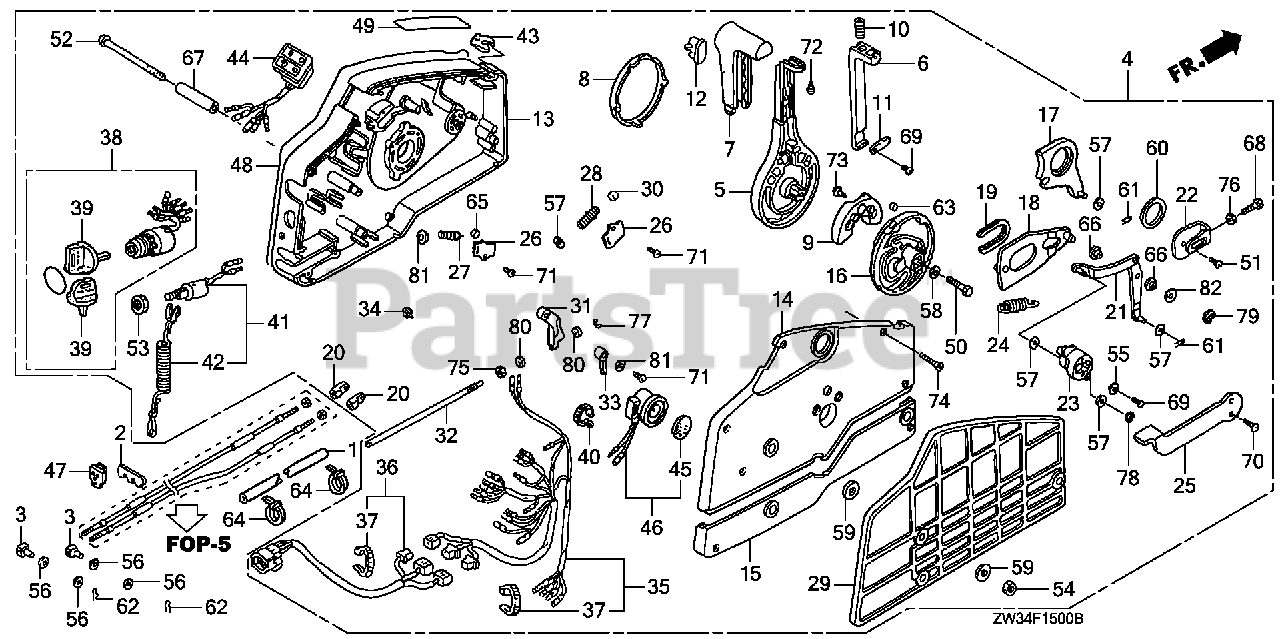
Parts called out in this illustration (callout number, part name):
4	S/R SW 2 LIGH MAN TL
4	BOX ASSY., REMOTE CONTROL (A/T)
4	BOX ASSY., REMOTE CONTROL (A/T)(HI-LEX)
5	HANDLE, REMOTE CONTROL
6	LEVER, HANDLE LOCK
7	GRIP, REMOTE CONTROL HANDLE
8	CAP, HANDLE
9	BLOCK, NEUTRAL LOCK
10	SPRING, REMOTE CONTROL HANDLE
11	PLATE, LEVER SETTING
12	COVER, GRIP
13	HOUSING, REMOTE CONTROL BOX (A)
14	HOUSING, REMOTE CONTROL BOX (B)
15	HOUSING, REMOTE CONTROL BOX (C)
16	WHEEL, CONTROL
17	ARM, SHIFT LINK
18	PLATE, SLIDING
19	COLLAR, SLIDING PLATE
20	PIVOT, SHIFT
21	ARM, LINK JOINT
22	BRACKET, LINK JOINT
23	WHEEL, ACCELERATOR
24	SPRING, ACCELERATOR WHEEL
25	LEVER, IDLE
26	PLATE, SPRING SETTING
27	SPRING, SHIFT CLICK
28	SPRING, CHOKE RETURN
29	SPACER, REMOTE CONTROL BOX
30	SPACER, CLICK SPRING
31	BLOCK, THROTTLE FRICTION
32	BOLT, FRICTION
33	SPACER, NEUTRAL SWITCH
34	SPACER, CABLE CLAMP
35	CABLE ASSY., REMOTE CONTROL (B)
36	CABLE ASSY., SWITCH PANEL
37	TIE, CABLE (2.4X92) (NATURAL)
38	SWITCH ASSY., COMBINATION
39	KEY ASSY., COMBINATION SWITCH (35100-ZV5-003 ONLY)
40	BAND (BLACK 3.5X140)
41	SWITCH ASSY., EMERGENCY STOP
42	WIRE, EMERGENCY
43	CLIP, EMERGENCY LOCK
44	LAMP ASSY., INDICATION (2-LED)
45	PLATE, TURN SIGNAL BUZZER
46	BUZZER, WARNING
48	PLATE, REMOTE CONTROL (CAUTION PICT=SILVER)
49	MARK, FAST IDLE
50	BOLT, HEX. (8X35)
51	SCREW, PAN (6X10)
52	SCREW (6X95)
53	NUT, HEX. (16MM)
54	NUT, HEX. (6MM)
55	WASHER, PLAIN (5MM)
57	WASHER, PLAIN (6MM)
58	WASHER, PLAIN (8MM)
59	WASHER (6MM)
60	WASHER (28MM)
61	PIN, LOCK (6MM)
63	PIN (6X6)
65	ROLLER, CLICK
66	COLLAR, LINK JOINT
67	COLLAR, DISTANCE (6X10X43.5)
68	BOLT, HEX. (5X16)
69	SCREW, PAN (5X10)
70	SCREW, OVAL (5X12)
71	SCREW, TAPPING (5X10)
72	SCREW, TAPPING (5X12)
73	SCREW, TAPPING (6X16)
74	SCREW, TAPPING (5X25)
75	NUT, HEX. (6MM)
76	NUT, HEX. (5MM)
77	E-RING (3MM)
78	E-RING (4MM)
79	E-RING (7MM)
80	WASHER, PLAIN (4MM)
81	WASHER, PLAIN (5MM)
82	WASHER, PLAIN (8MM)
